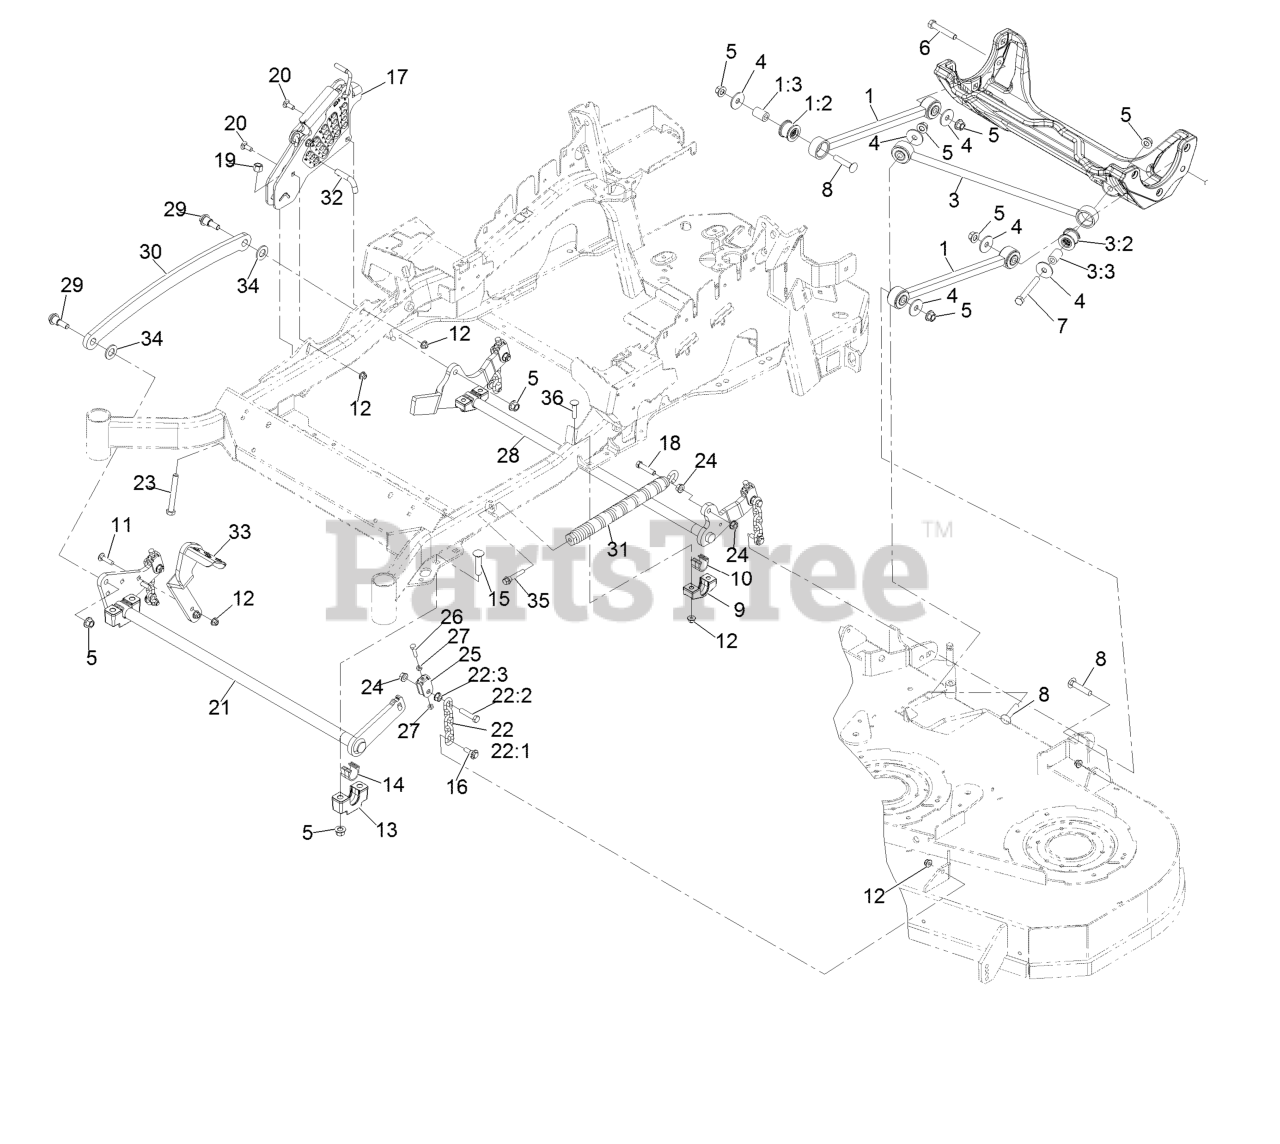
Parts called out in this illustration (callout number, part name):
1	Long Strut ASM
1:2	Bushing-Suspension, Rubber
3	Panhard Rod ASM
3:2	Bushing-Suspension, Rubber
5	Nut-Lock 1/2-13
6	Screw-HH 1/2-13 X 3
7	Screw-HH 1/2-13 X 4
8	Bolt-Carriage 1/2-13 X 2 1/2
9	Support-Cross Shaft, Bearing Rear
10	Bearing-Cross Shaft, Rear
11	Bolt-Carriage 3/8-16 X 1 1/2
12	Nut-Nyloc 3/8-16 Flg
13	Support-Cross Shaft, Bearing
14	Bearing-Cross Shaft, Front
15	Bolt-Carriage 1/2-13 X 2 1/2 Spl Neck
16	Screw-Hex Flange 3/8-16 X .80
17	HOC ASM
18	Screw-HH 7/16-14 X 2
19	Nut-Nyloc 1/2-13
20	Bolt-Carriage 3/8-16 X 1
21	Decklift-Front
22	Deck Lift Chain ASM
22:1	Chain-Lift, Deck
22:2	Screw-HH 7/16-14 X 2
22:3	Nut-Whizlock 7/16-14
23	Bolt-HH 1/2-13 X 4 Tap
24	Nut-Whizlock 7/16-14
25	Yoke-Adjust, Deck
26	Screw-HH 5/16-18 X 1 1/4
27	Nut-Jam 5/16-18
28	Lift-Deck, Rear
29	Screw-Shoulder HHF 1/2-13 X 1.12
30	Link-Lift, Deck
31	Spring-Extension
32	Pin-HOC
33	Lever-Foot
34	Washer-3/4 SAE
35	Screw-Shcs 3/8-16 X 2.212
36	Bolt-Carriage 3/8-16 X 2 1/4
